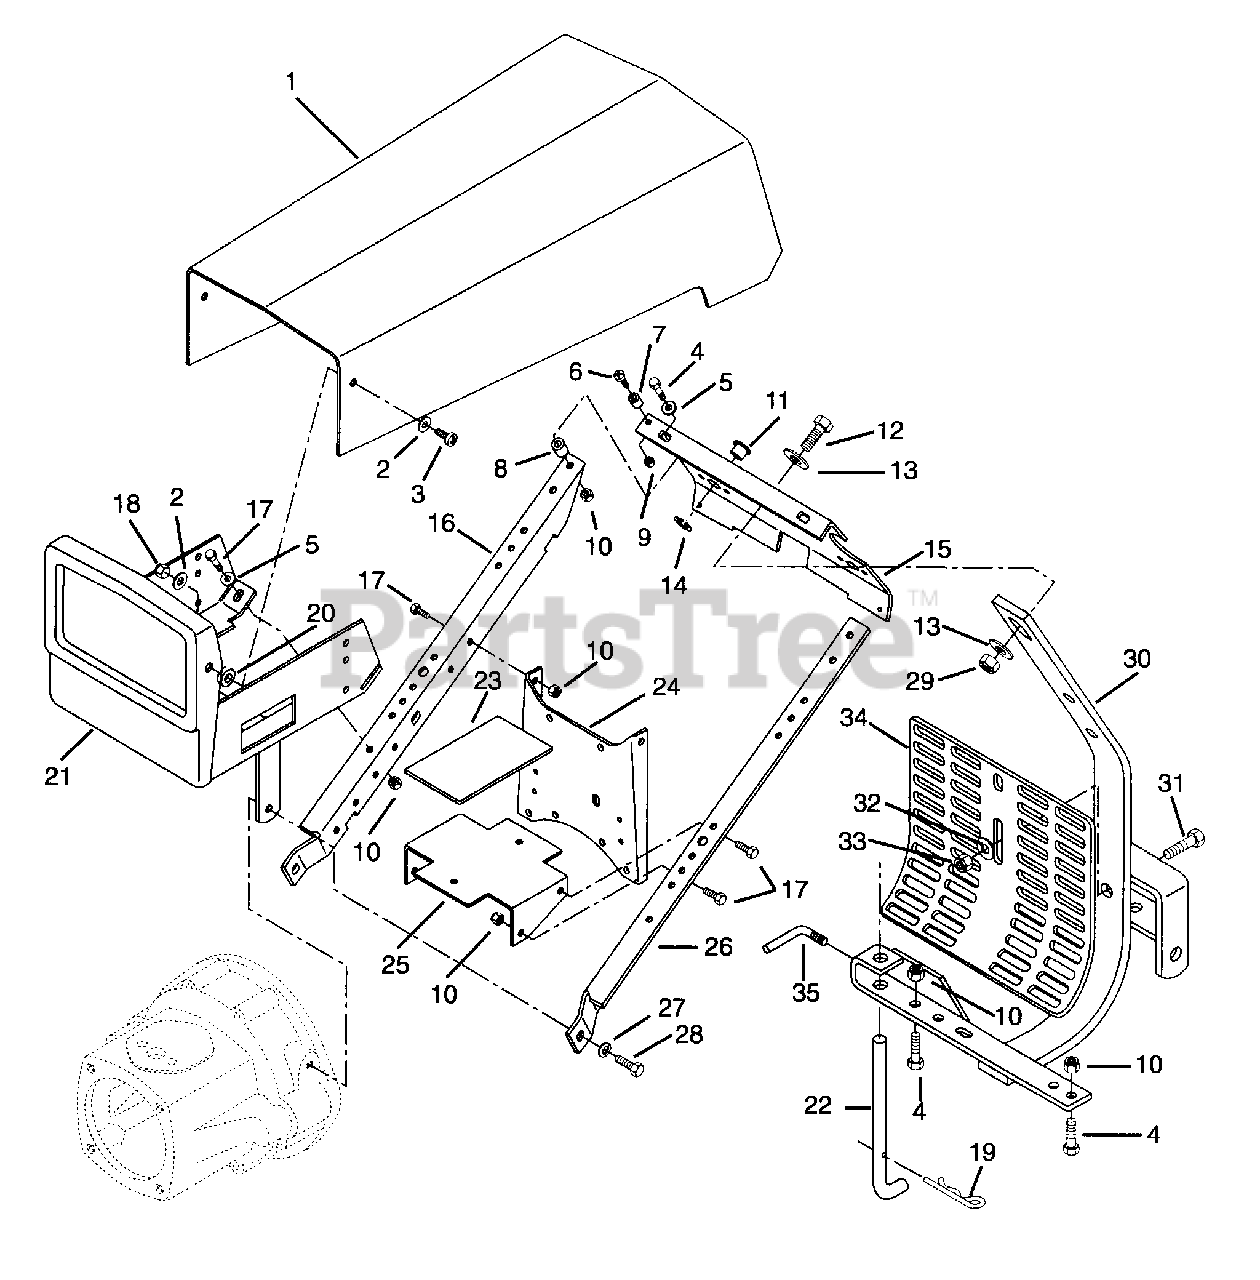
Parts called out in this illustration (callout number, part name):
1	Hood
1	Hood and Decal
2	Washer-Flat-Steel .281 x .620 x .065
3	Screw-Machine .250-20 x 1
4	Bolt-Hex .38-16 x 1.50 Grade 5
5	Washer-Flat-Steel .406 x .812 x .065
6	Screw-Machine 6-32 x .75
7	Bumper
8	Bushing
9	Nut-Locking-Nylon 6-32
10	Nut-Locking-Center.375-16 Grade 2
11	Bushing-Flange .515 x .750 x .745 x 1.00
12	Bolt-Hex .625-11 x 2.00
13	Washer-Flat-Steel .656 x 1.31 x .095
14	Ring-Retaining 1.000 x .748
15	Plate, Instrument
16	Support, Handle Bar Right Hand
17	Bolt-Hex .380-16 x .75
18	Nut-Locking-Center .250-20 Grade 2
19	Pin-Hair-Internal .15 x 2.937
20	Bushing, Flange 280 x .750 x .318
21	Weldment, Battery Bracket
22	Stand, Lick
23	Pad, Gas Tank
24	Bracket
25	Bracket, Tank Support
26	Support, Handle Bar Left Hand
27	Washer-Lock .50 Reg.
28	Bolt-Hex .50-13 x 1 Grade 5
29	Nut-Locking-Nylon .625-11 Grade 2
30	Weldment, Hitch 10 & 12 HP
31	Bolt-Hex .50-13 x 1.50 Grade 5
32	Washer-Flat-Steel .563 x 1.38 x .109
33	Nut-Locking-Center .50-13 Grade 5
34	Guard, Engine
35	Handle, Adjusting
